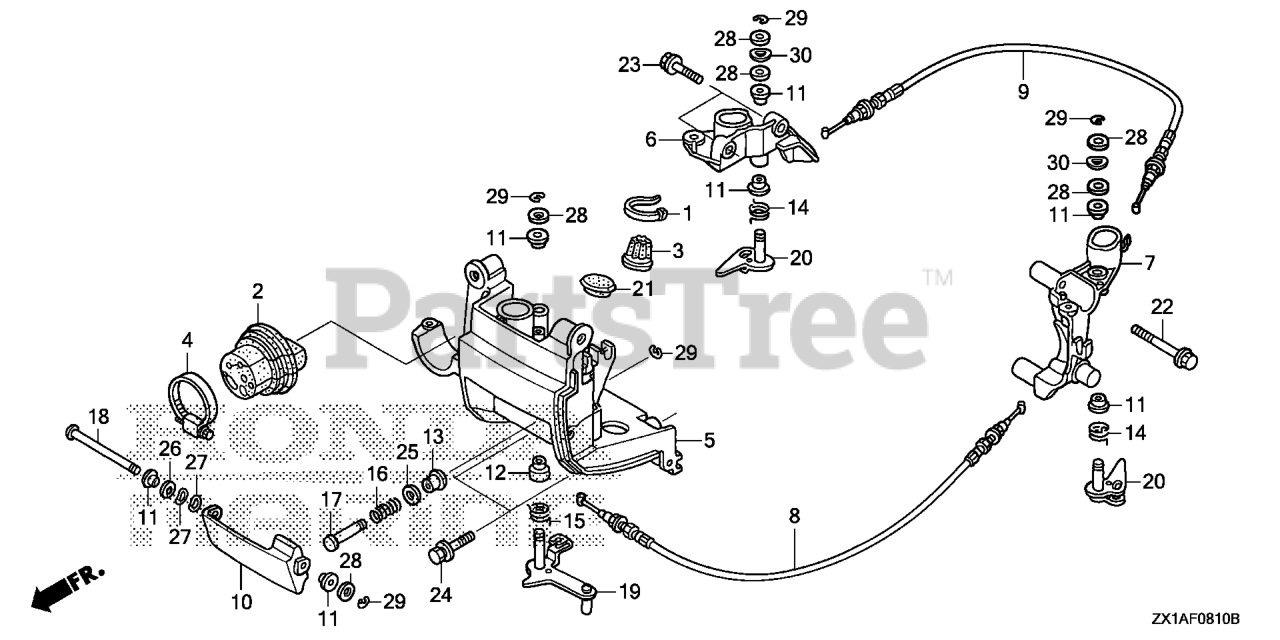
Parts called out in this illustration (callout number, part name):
1	BAND (BLACK 3.5X140)
2	GROMMET, REMOTE CONTROL CABLE
3	GROMMET, CASE (LOWER) (C)
4	BAND, CASE GROMMET (LOWER)
5	BRACKET, FR. COVER (LOWER) *NHB14M* (AQUA MARINE SILVER METALLIC)
5	BRKT,UNDER*NH565*
6	BRACKET, R. SIDE COVER
7	BRACKET, L. SIDE COVER
8	CABLE A, COVER LOCK
9	CABLE B, COVER LOCK
10	LEVER, COVER LOCK *NHB14M* (AQUA MARINE SILVER METALLIC)
10	LEVER, COVER LOCK *NH565* (GRAND PRIX WHITE)
11	BUSH A, COVER LOCK
12	BUSH A, COVER LOCK
13	BUSH B, COVER LOCK
14	SPRING, COVER LOCK HOOK
15	SPRING, COVER LOCK HOOK
16	SPRING, LOCK LEVER RETURN
17	SHAFT, COVER OPEN
18	SHAFT, FR. LOCK
20	LOCK, SIDE
21	CAP, L. SIDE COVER
22	BOLT, FLANGE (8X55)
23	BOLT, FLANGE (6X22)
24	BOLT-WASHER (8X30)
25	WASHER, PLAIN (8MM)
26	WASHER, PLAIN (10MM)
27	WASHER, WAVE (10MM)
28	WASHER, PLAIN (8MM) Use from Frame SN 4800713.
29	E-RING (6MM)
30	WASHER, WAVE (8MM)
